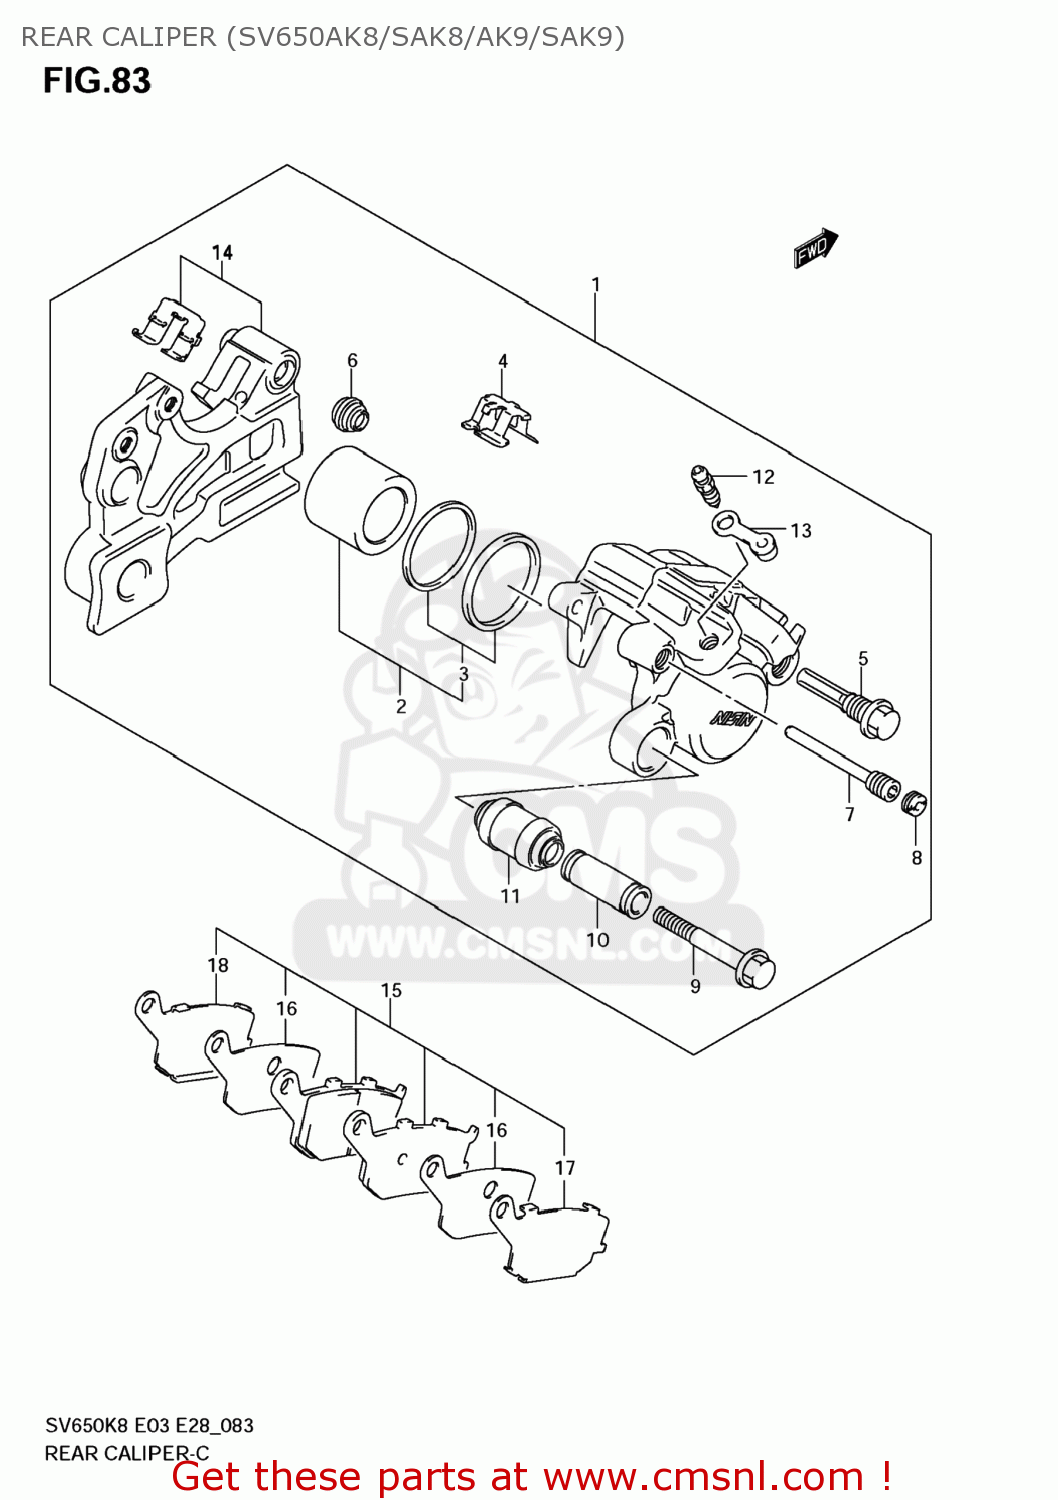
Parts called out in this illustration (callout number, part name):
1	CALIPER ASSY,RE
2	PISTON SET
3	SEAL SET,PISTON
4	SPRING,PAD
5	BOLT
6	BOOT
7	PIN,PAD
8	PLUG,PIN
9	BOLT
10	SLEEVE
11	BOOT,SLEEVE
12	BLEEDER
13	CAP,BLEEDER
14	BRACKET
15	PAD & RETAINER
16	INSULATOR
17	RETAINER
18	RETAINER
